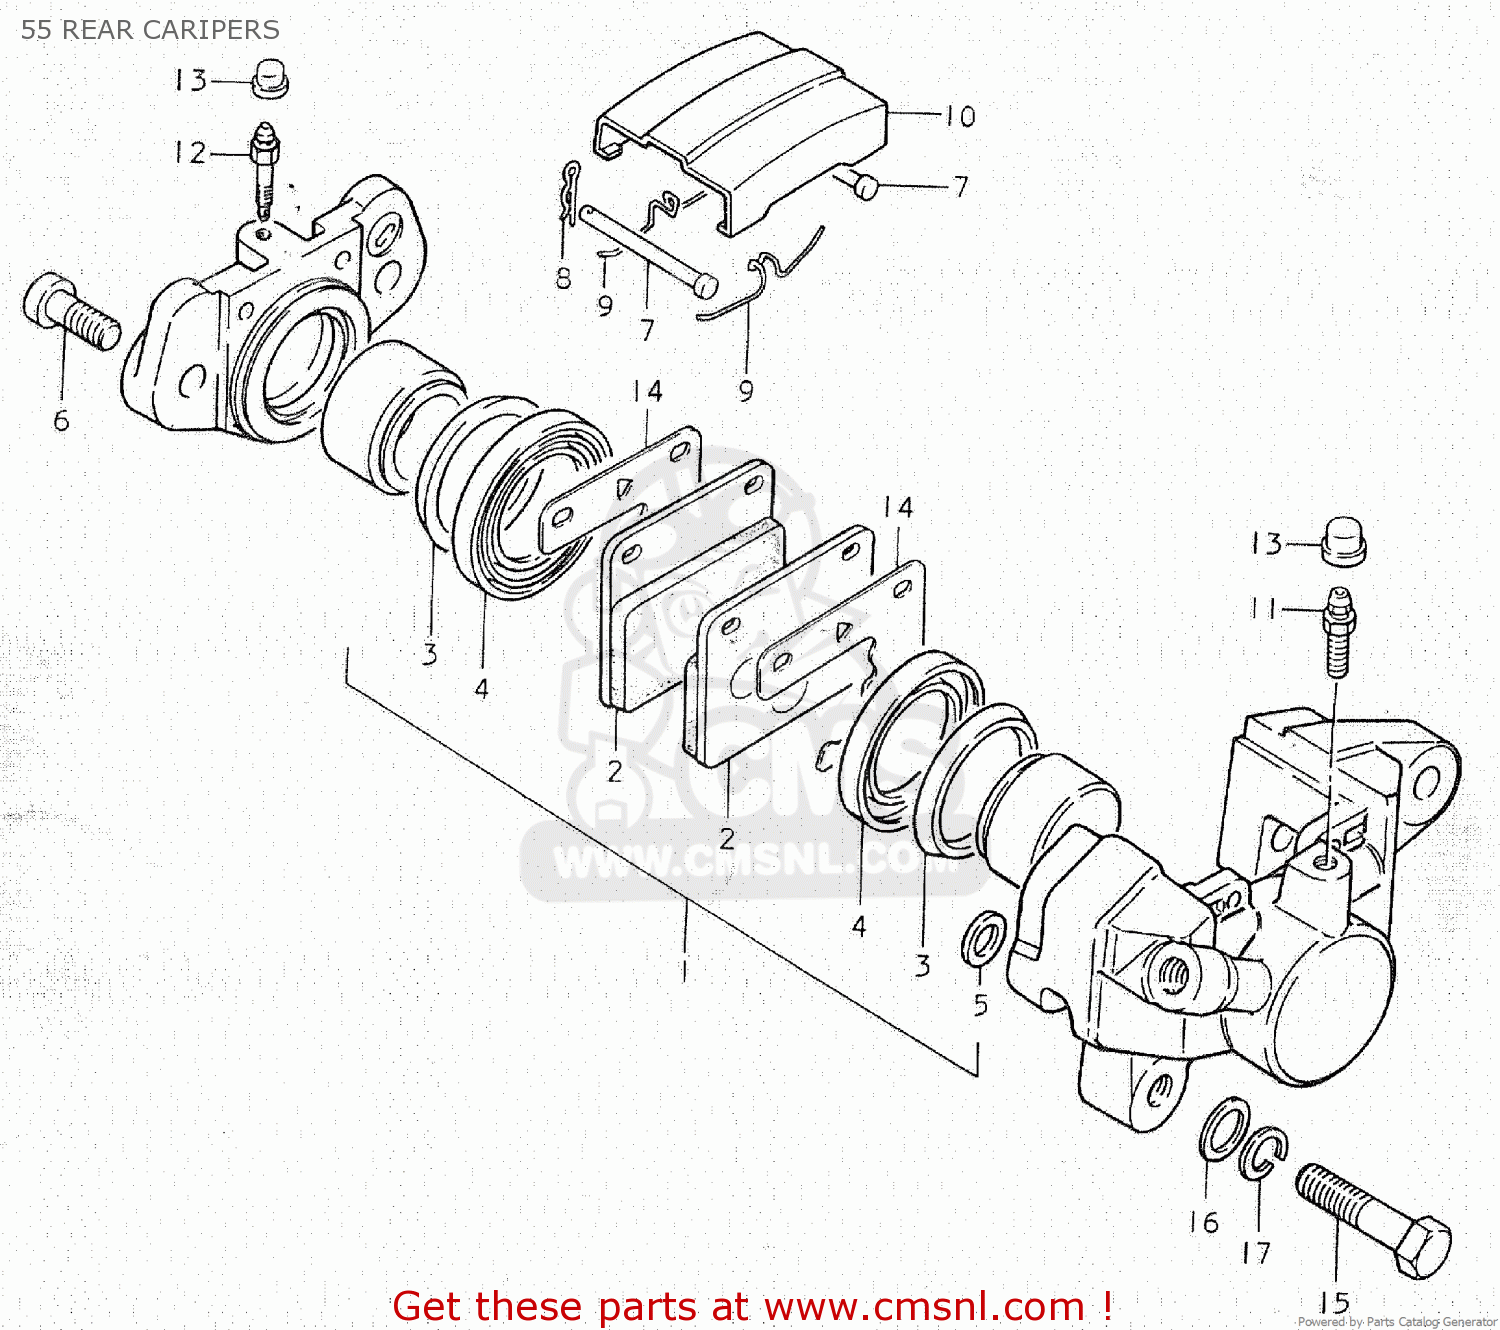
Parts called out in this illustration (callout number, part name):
1	PISTON SET
2	PAD,BRAKE
3	SEAL,PISTON
4	BOOT,PISTON
5	SEAL,PISTON
6	BOLT,HOUSING
7	PIN,PAD
8	CLIP,PAD PIN
9	SPRING
10	COVER,DUST
11	BLEEDER
12	BREATHER
13	CAP,BREATHER
14	SHIM,RR CALIPER
15	BOLT 10X34
16	WASHER
17	LOCK WASHER
